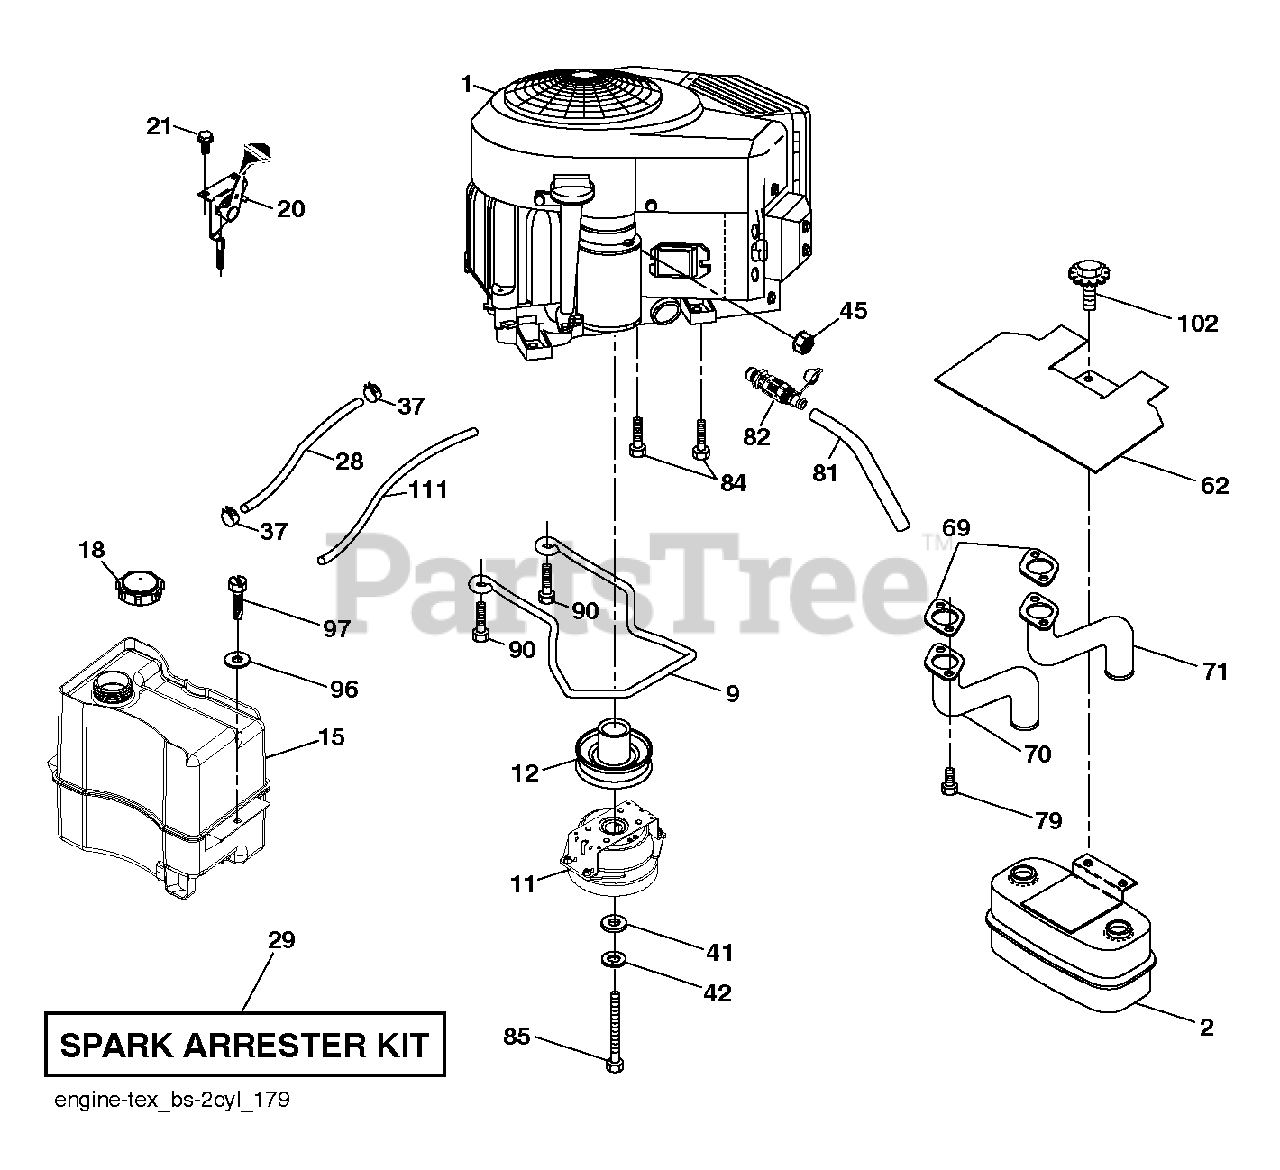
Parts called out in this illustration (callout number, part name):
2	MUFFLER.ASM.TWN.EXTNDED.DFLCTR
9	KEEPER.BELT.ENG.3.25"2BOLT.PNT
11	Clutch, Ogura 5.0Pd Gt1.5A-Eh07
12	PULLEY.ENGINE.ENX
15	TANK.ASM.FRT.2.5 GAL.W/CAP.EPA
18	CAP.FUEL.2 WAY VENT
20	Throttle, Cobra 38" Readstart.Bk
21	SCREW.#10 X 0.750.BOS (2 2)
28	LINE.FUEL.20"FRONT.EMI
29	SPARK ARRESTOR KIT
37	HOSE CLAMP
42	LOCKWASHER
45	NUT
62	SHIELD.HEAT.MUFFLER
69	GASKET.MUFFLER
70	EXHAUST.TUBE.LH.BS/TWIN
71	EXHAUST.TUBE.RH.B&S.TWIN.INTEK
79	SCREW.SOCKET.HEAD.5/16-18
81	TUBE, DRAIN OIL ASM.
82	VALUE.OIL.DRAIN
84	SCREW.3/8-16
85	Hex Bolt, 7/16-20 X 3.75 Gr5 Red
90	SCREW 3/8-16X1
97	SCREW HEXWSHR 1/4-20X3/4
102	SCREW
111	RP PURGE LINE
